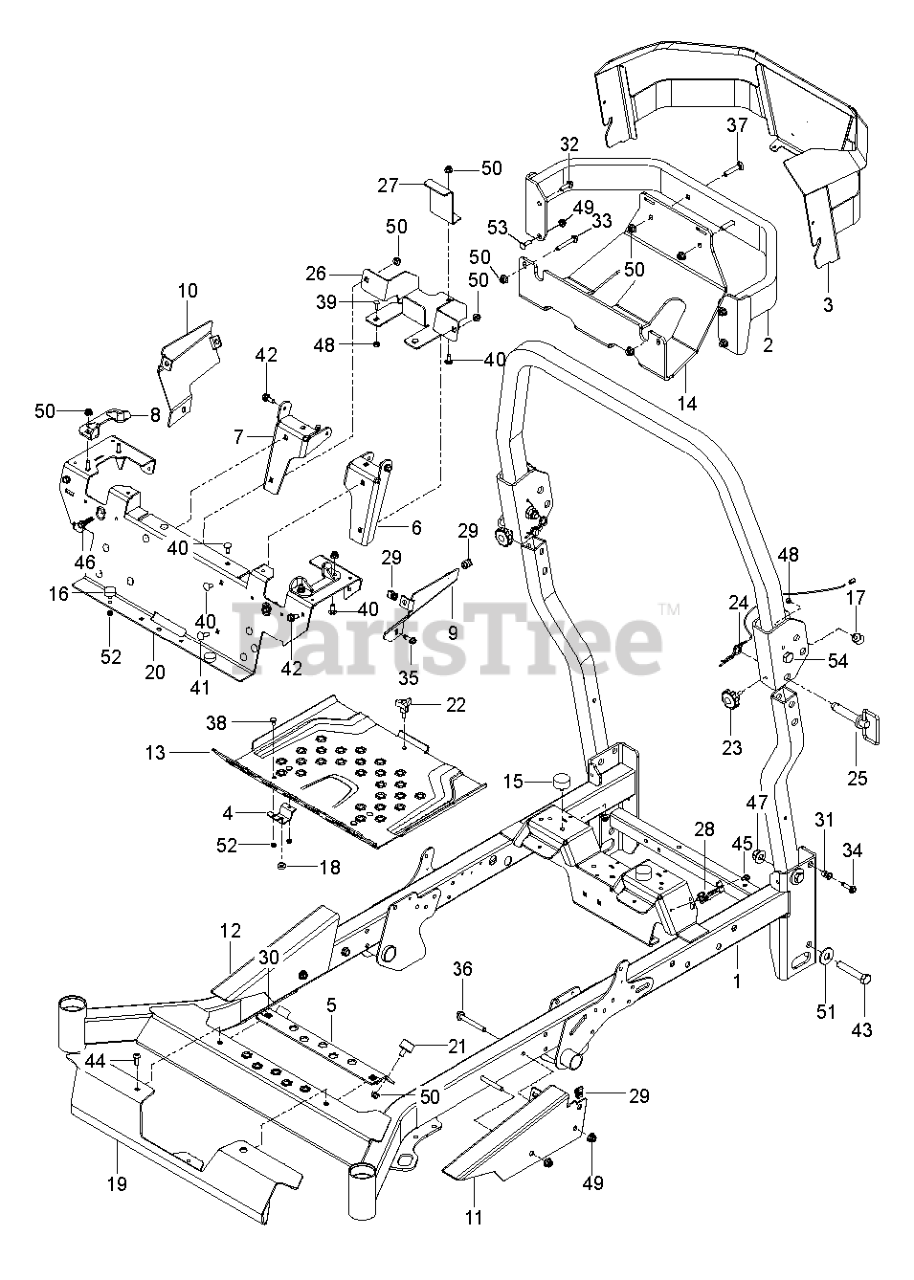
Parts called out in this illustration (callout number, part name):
1	FRAME.W/DECALS.48-60".ORG
2	BUMPER, REAR, ORG
2	BUMPER.REAR.ORANGE
3	GUARD.ENGINE.GREY.498
3	GUARD.PNT.ENGINE.GREY
4	COVER.PNT.VALANCE.PZ.GREY
5	BRACKET.PNT.ISOLATOR.SUPPT.BLK
6	BRACKET.PNT.MTG.SEAT.LH.EDIP
7	BRACKET.PNT.MTG.SEAT.RH.EDIP
8	CABLE.YOKE.PARK.BRAKE
9	PANEL.PNT.CLOSE.OUT.LH.ORG
9	PANEL CLOSE OUT LH ORANGE MS-6
10	PANEL.PNT.CLOSE.OUT.RH.ORG
10	PANEL CLOSE OUT RH ORANGE MS-6
11	PANEL.PNT.WEDGE.LH.ORG
12	PANEL.PNT.WEDGE.RH.ORG
13	PLATE.PNT.FOOTREST.PZ.ORANGE
14	PLATE, SKID GRAY
14	PLATE SKID, Z500 LONG YAMAHA G
14	PLATE.SKID.GRAY
15	BUMPER 5/16-18
16	BUMPER, 1/4-20 STUD, 1/4
17	BUMPER, MALE STUD, 1/4-20
18	GROMMET, BUMPER
19	COVER.PNT.VALANCE.PZ.GREY
20	CROSS.MEMBER.PNT.SEAT.FRONT.OR
21	ISOLATOR.PZ.FOOTREST
22	KNOB W/STUD
23	KNOB.5/16-18X1"BLACK
24	PIN.HAIR.DOUBLE.LOOP.W/LANYARD
25	PIN.ROPS.W/HANDLE
26	PLATE.PNT.BATTERY.EDIP
27	Brackets
27	BRACKET.PNT.MOUNT.BATTERY.EDIP
28	BRACKET.FUSE.RELAY.HOUSING.PZ
29	U-CLIP 5/16-18 NUT RETAINER
30	SCREW.BUTTON.HEAD.TORX.3/8-161
31	NUTSERT 5/16-18 THICK GRIP
32	HHFS 3/8-16 X 1 GRD 5 ZD
33	HHFS 5/16-18 X 2.25 GD 5
34	HHFS 5/16-18 X 1.25 TPBLT GD 5
35	SCREW
36	HHFS 3/8-16 X 3 GRD 5 ZD
37	RHSNB 3/8C X 2
39	1/4-20X3/4 CARR BLT
40	BOLT 5/16C X 3/4" CARRIAGE
41	RHSNB 5/16C X 1
42	BOLT, SHOULDER
43	5/8-11 X 3-1/2 HHB GRADE 5
44	SCREW.BUTTON.HEAD.TORX.3/8-161
45	SCREW
46	SCREW.SHAKEPROOF.1.25.BLACK
47	NUT 5/8-11 FLG NYLOC ZD
48	NUT.1/4-20.HEX.NYLOC.ZD
49	NUT 3/8-16 HEX FLG NYLOC ZD
50	5/16-18 NYLOC FLANGE NUT
51	WASHER, 5/8 FLAT
52	JAM NUT 1/4C (2 2 PW01)
53	BOLT.3/8-14X1.25
54	BOLT.HEXAG.5/8-11X4-1/4.G5.ZPY
